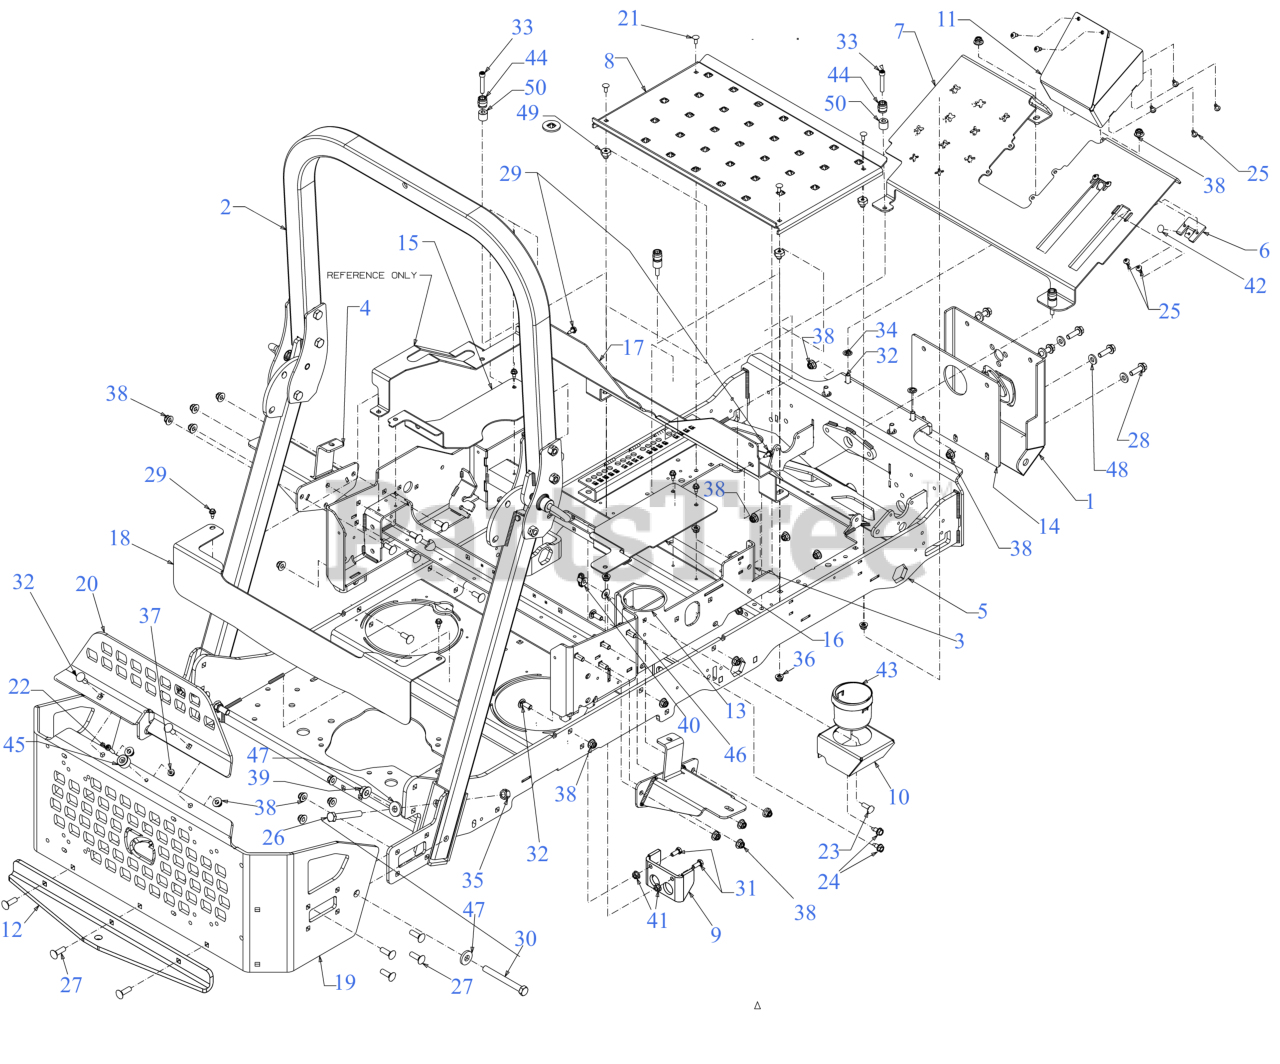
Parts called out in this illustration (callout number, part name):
2	PRO Z ROPS KIT
3	SEAT FRAME
4	FUEL TANK MOUNT
5	FRAME
6	REVERSE PEDAL STOP BRACKET
10	LOWER CUP HOLDER
14	FRONT MOUNTING PLATE SPACER
15	SEAT COVER PANEL (LH)
16	SEAT COVER PANEL (RH)
17	SEAT BOX COVER (FRONT)
18	SEAT BOX COVER (REAR)
19	BUMPER (LOWER RR)
20	BUMPER (UPPER RR)
21	CARRIAGE BOLT 1/4-20 x .62
22	MACHINE SCREW 1/4-20:1
23	CARRIAGE BOLT 5/16-18 x 1.00
24	SCREW 5/16-18 x .750
25	SCREW 1/4-20 x .5
26	SCREW 1/2-20 x 3.50 GR5
27	CARRIAGE BOLT 3/8-16 X1.25 GR5
28	SCREW 3/8-16 x 1.25 GR5
29	SCREW 1/4-20X.625
30	SCREW 1/2-13 x 4.5 GR 5
31	SCREW 5/16-18 x .75 GR5
32	CARRIAGE BOLT 3/8-16 x 1.00 GR5
33	SCREW 5/16-18X1.75 GR5
36	FLANGE LOCK NUT 5/16-18
37	FLANGE LOCK NUT
40	WING NUT 5/16-18
41	FLANGE NUT
42	RATCHET CLIP
44	RADIAL BUMPER
46	FLAT WASHER
47	FLAT WASHER .531 x 1.25 x .181
48	FLAT WASHER
49	SHOULDER SPACER
